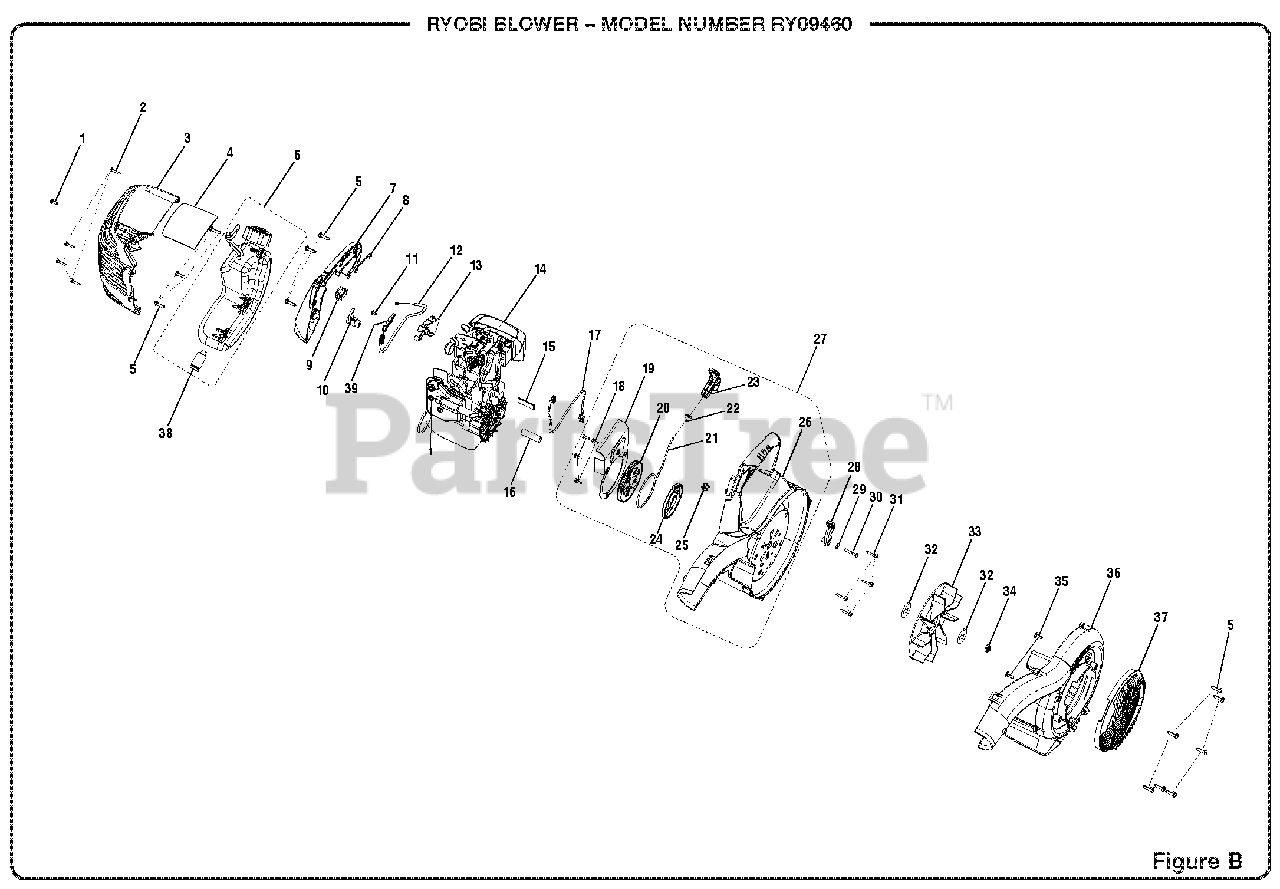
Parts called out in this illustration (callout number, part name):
1	Screw (M5 x 10 mm)
2	Screw (M4 x 18 mm)
3	Engine Housing
4	Heat Shield
5	Screw (10-14 x 3/4 in, T.F.)
6	Fuel Tank Assembly w/Cap
7	Handle Cover
8	Ground Wire
10	Trigger Lock
11	Screw (M3.5 x 7.5 mm)
12	Throttle Cable
14	Power Head Assembly
17	Electric Wire Assembly
18	Screw (M4 x 12 mm)
20	Starter Pulley
21	Starter Rope
23	Starter Grip
24	Container Spring Assembly
26	Inner Volute
27	Lower Housing w/Starter
28	Cruise Lever
30	Cruise Lever Screw
31	Screw (M4 x 23 mm)
33	Fan
34	Lock Nut (3/8 in.)
35	Screw (10-14 x 1/2 in.)
36	Outer Volute
37	Air Inlet Cover
38	Fuel Filter
39	Throttle Lever
